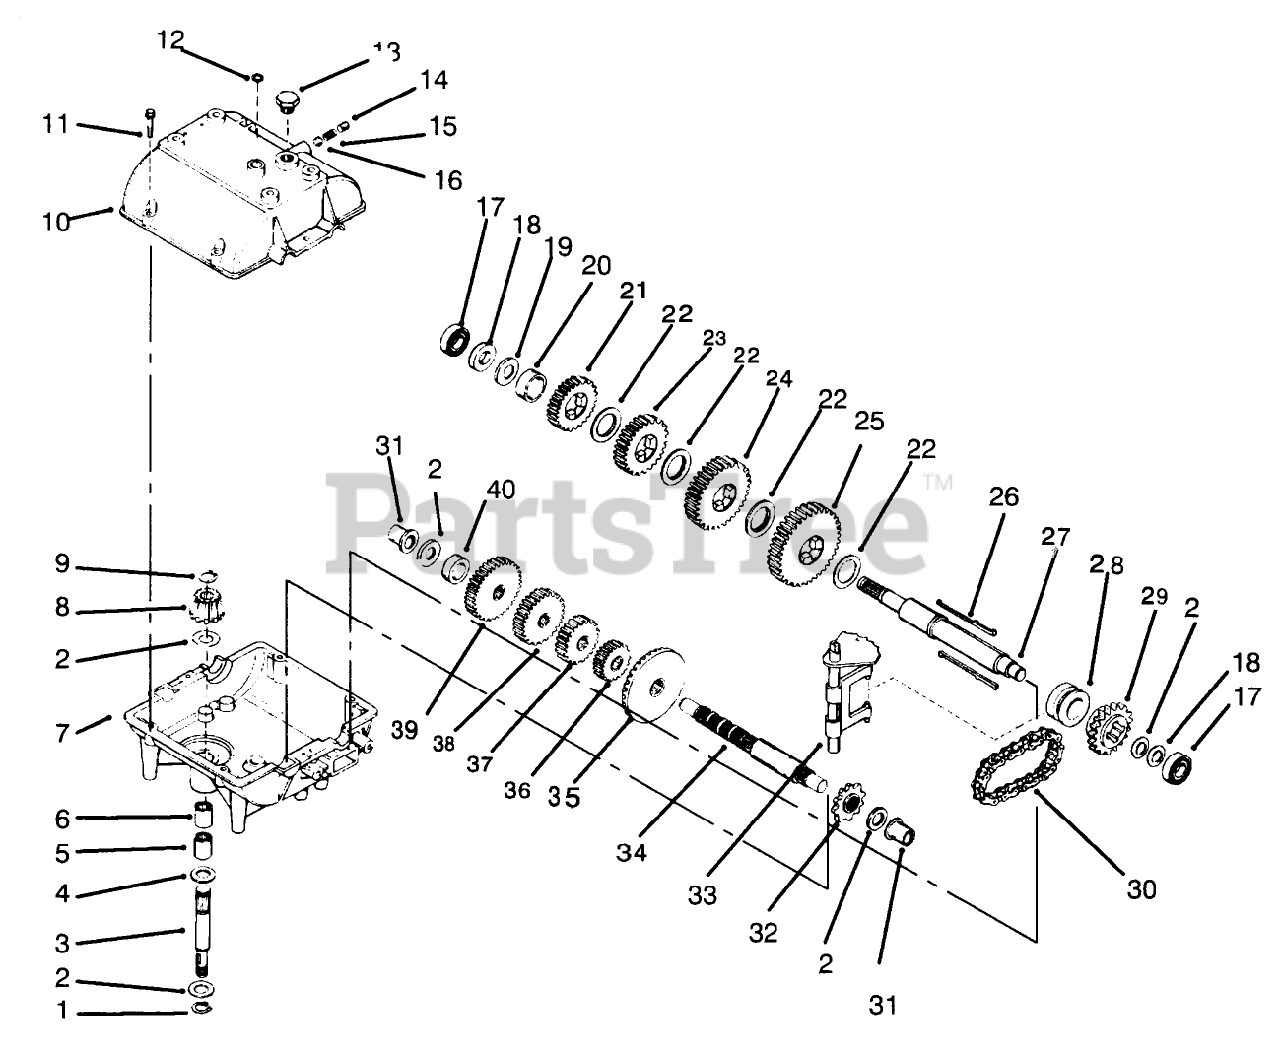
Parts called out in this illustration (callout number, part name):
1	Ring-Snap
2	Washer
3	Shaft-Input
4	O Ring
5	Bearing-Needle
6	Bearing-Needle
7	Case-Transmission
8	Bevel Pinion-Input
9	Ring-Retainer
10	Cover-Transmission
11	Ring Set (.020 O S)
12	Cut Seal-Square
13	Plug
14	Screw-Set
15	Spring
16	Ball-Steel
17	Bearing-Ball
18	Thrust Washer
19	Washer
20	Spacer
21	Gear-Spur, 25 Teeth
22	Washer
23	Gear-Spur 27 Teeth
24	Gear-Spur, 30 Teeth
25	Gear-Spur, 35 Teeth
26	Key
27	Shaft-Output/Brake
28	Collar-Shift
29	Sprocket-18 Teeth
30	Chain-Roller #41
31	Bushing-Flange
32	Sprocket-9 Teeth
33	Rod and Fork ASM
34	Countershaft
35	Gear-Bevel, 42 teeth
36	Gear-Spur 15 Teeth
37	Gear-Spur, 20 Teeth
38	Gear-Spur 23 Teeth
39	Gear-Spur, 25 Teeth
40	Spacer
